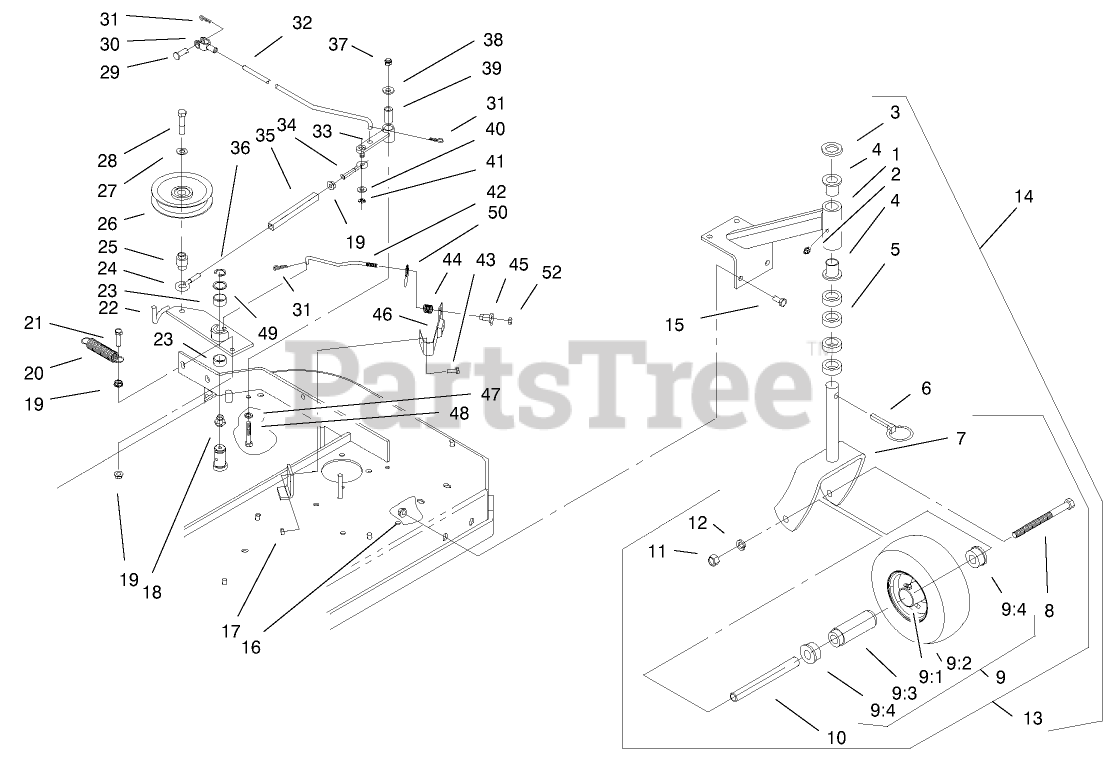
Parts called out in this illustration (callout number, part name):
1	Support-Caster
2	FITTING-GREASE
3	Washer
4	Bearing-Flanged
5	Spacer
6	Pin
7	Fork
8	SCREW-HH
9	WHEEL AND TIRE ASM
9:1	Wheel Hub ASM
9:2	Tire
9:3	Bearing
9:4	Bushing
10	Spacer
11	NUT-HH
12	WASHER-LOCK
13	Caster Wheel ASM
14	Caster/Mount ASM
15	SCREW-HH
16	NUT-HHF, WHIZ
17	NUT-LOCK, NI
18	FITTING-GREASE
19	NUT-HF
20	Spring
21	SCREW-HH
22	Engagement Arm w/Bushings
23	Bearing-Sleeve
24	Eye Bolt
25	Bushing
26	Pulley-Idler
27	WASHER-BELLEVILLE
28	SCREW-HH
29	Pin-Clevis
30	Yoke
31	PIN-COTTER
32	Linkage-Assist Arm
33	Assist Arm ASM
34	Eye Bolt
35	Turnbuckle Body
36	RING-RETAINING, EXT
37	NUT-LOCK, NI
38	WASHER-FLAT
39	Tube-Pivot
40	WASHER-PLAIN
41	E-Ring
42	Rod-Brake
43	SCREW-HH
44	Spring-Compression
45	Spacer-Flanged
46	Pad/Spring ASM
47	Washer-Lock
48	SCREW-HH
49	Spindle Washer
50	Ring-Push On
52	NUT-LOCK, NI
